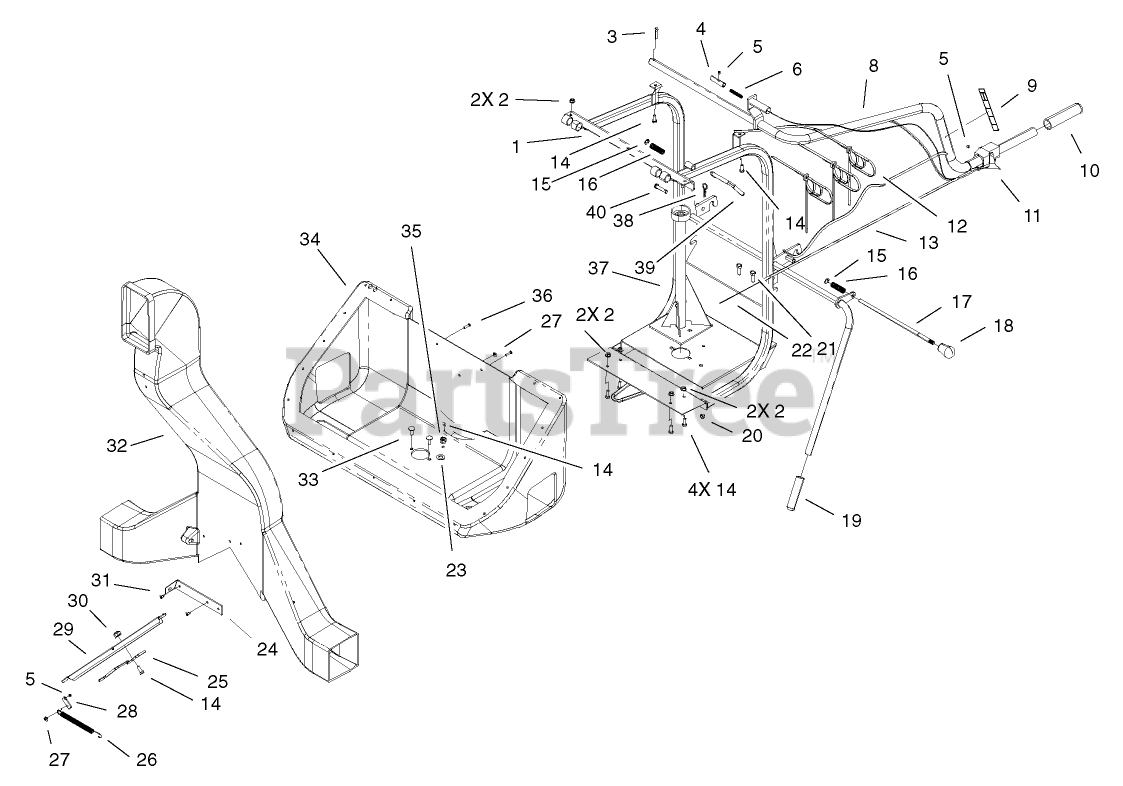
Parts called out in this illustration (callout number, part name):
1	FRAME
2	NUT-HF
3	PIN-COTTER
4	PIN-LOCK
5	SCREW-SET, HSH
6	SPRING
8	ARM-DUMP
9	LABEL-DUMP ARM OPERATION
10	GRIP-HANDLE
12	TIE-CABLE
13	SHIELD-CABLE
14	SCREW-HH
15	RING-RETAINER
16	SPRING
17	PIN-HITCH
18	KNOB-OVAL
19	GRIP-HANDLE
20	NUT-LOCK, NI
21	SCREW-HH
22	CABLE
23	WASHER-FLAT
24	BRACKET-REINFORCING
25	LEVER-DOOR
26	SPRING
27	WASHER-CAP
28	END-CABLE
29	DOOR-AIR
30	NUT-HEX
31	SCREW-TAP
32	DOCK-AIR
33	SCREW-CARR
34	HOPPER-BOTTOM
35	NUT-LOCK, NI
36	SCREW-HWH, THREAD FORMING
38	HAIRPIN
40	PIN-HITCH
